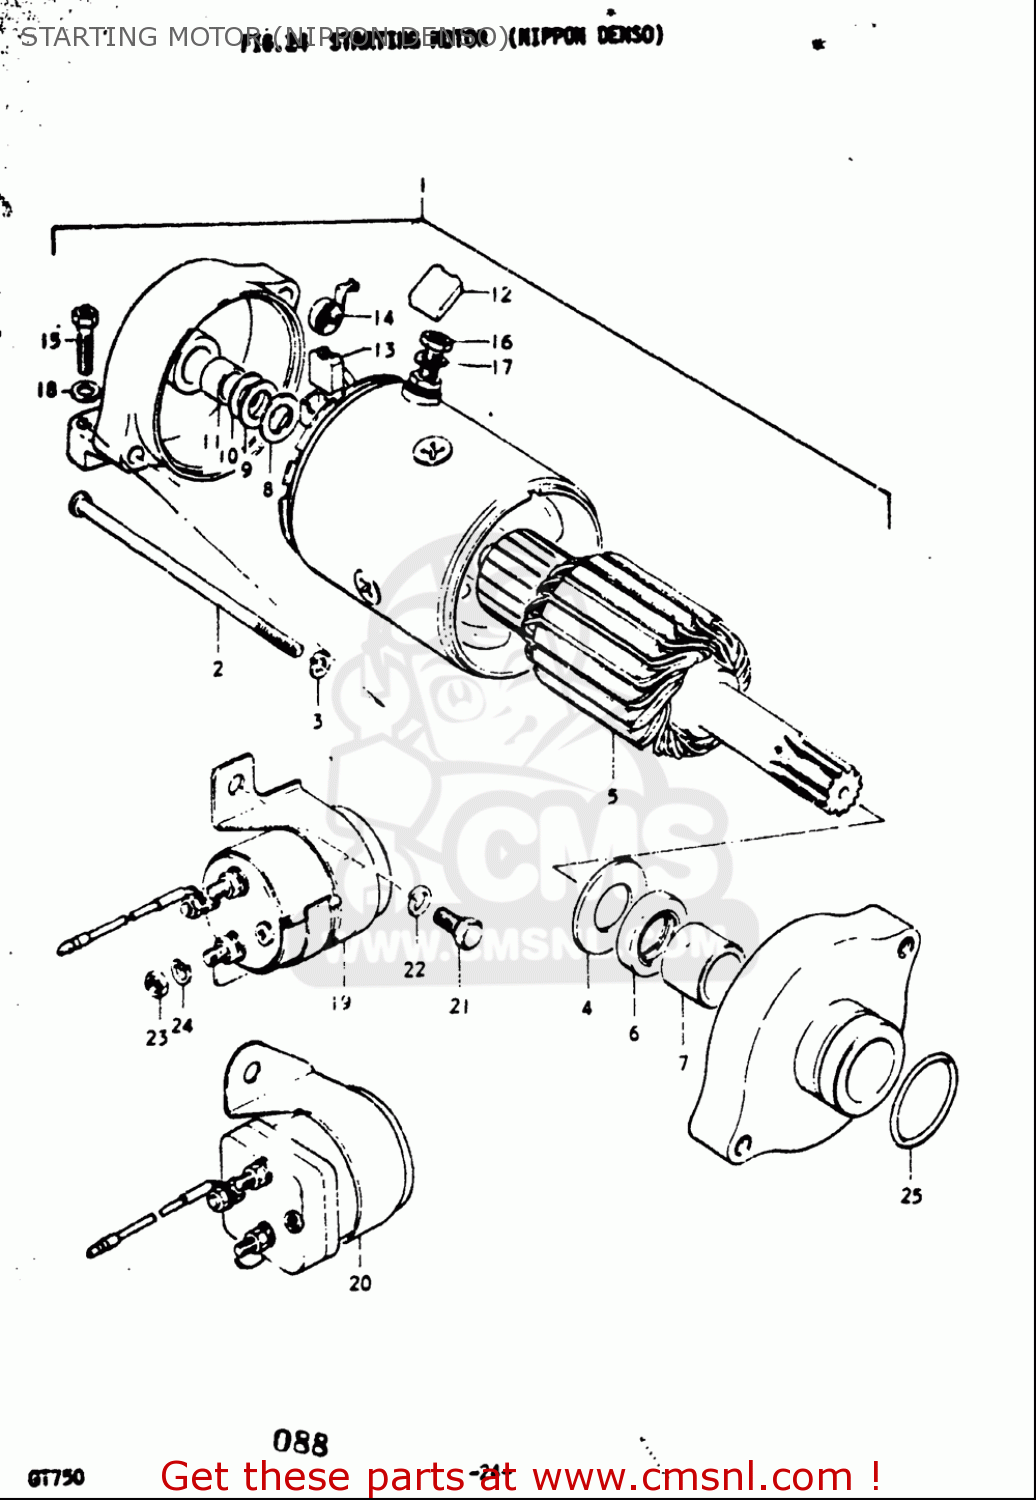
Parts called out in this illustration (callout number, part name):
1	MOTOR ASSY,STARTING
3	WASHER,LOCK
8	SHIM, (1)
9	SHIM, (2)
10	SHIM, (3)
14	SPRING
15	SCREW (6X25)
16	NUT
17	WASHER,LOCK
18	WASHER
19	RELAY ASSY,STARTING MOTOR
20	RELAY ASSY,STARTING MOTOR
21	BOLT
22	WASHER,LOCK
23	NUT
24	WASHER,LOCK
25	O-RING
